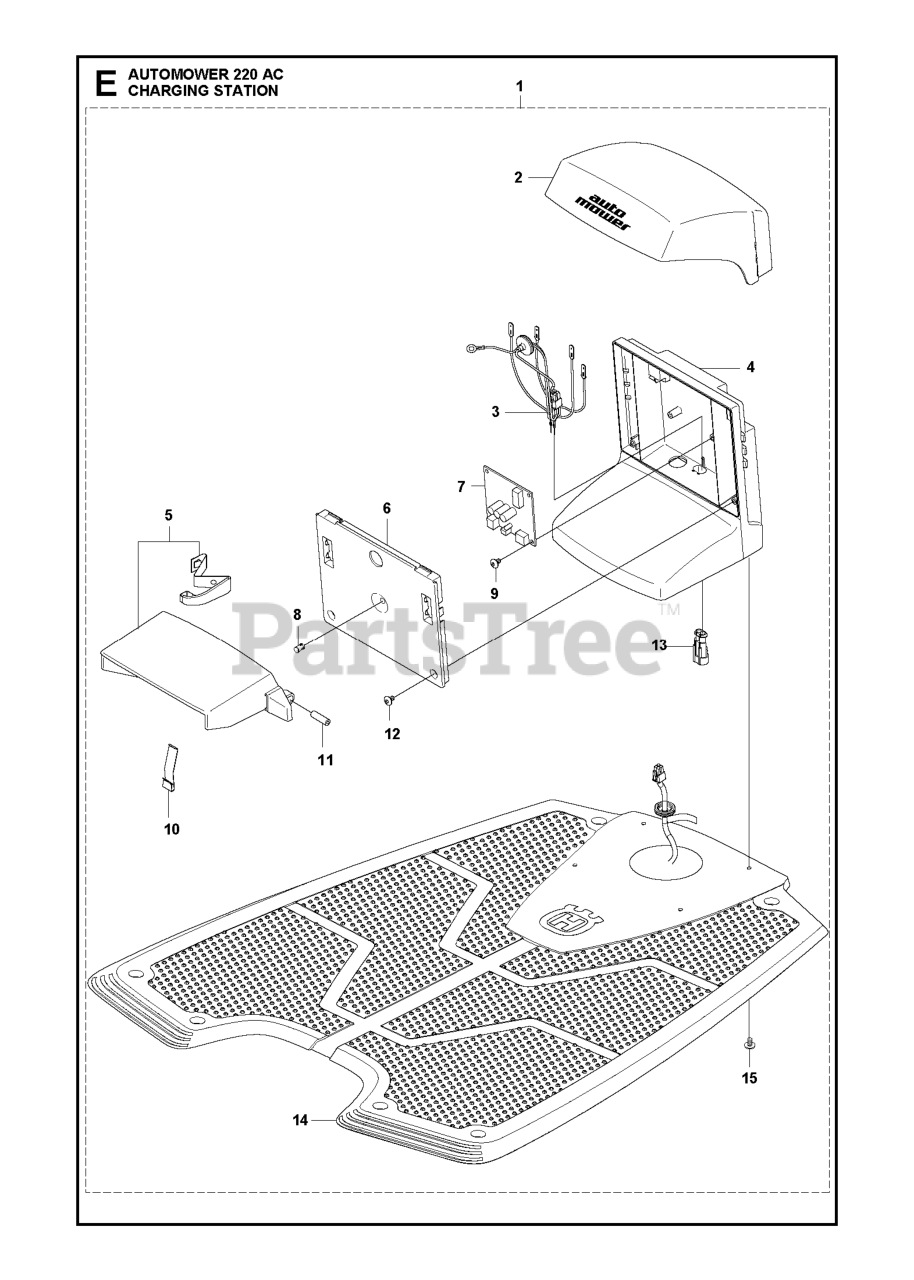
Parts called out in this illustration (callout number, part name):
1	CHARGING STATION
2	CS / TOWER COVER
3	WIRING ASSY LOOM
4	BODY CHARGING TOWER
7	CIRCUIT BOARD ASSY PCBA GEN BO
7	PRINTED CIRCUIT ASSY PCBA GEN
8	LENS
9	SCREW SILVER 10MM
12	SCREW 14MM
14	BASE ASSY CHARGING STATION
15	SCREW 14MM
